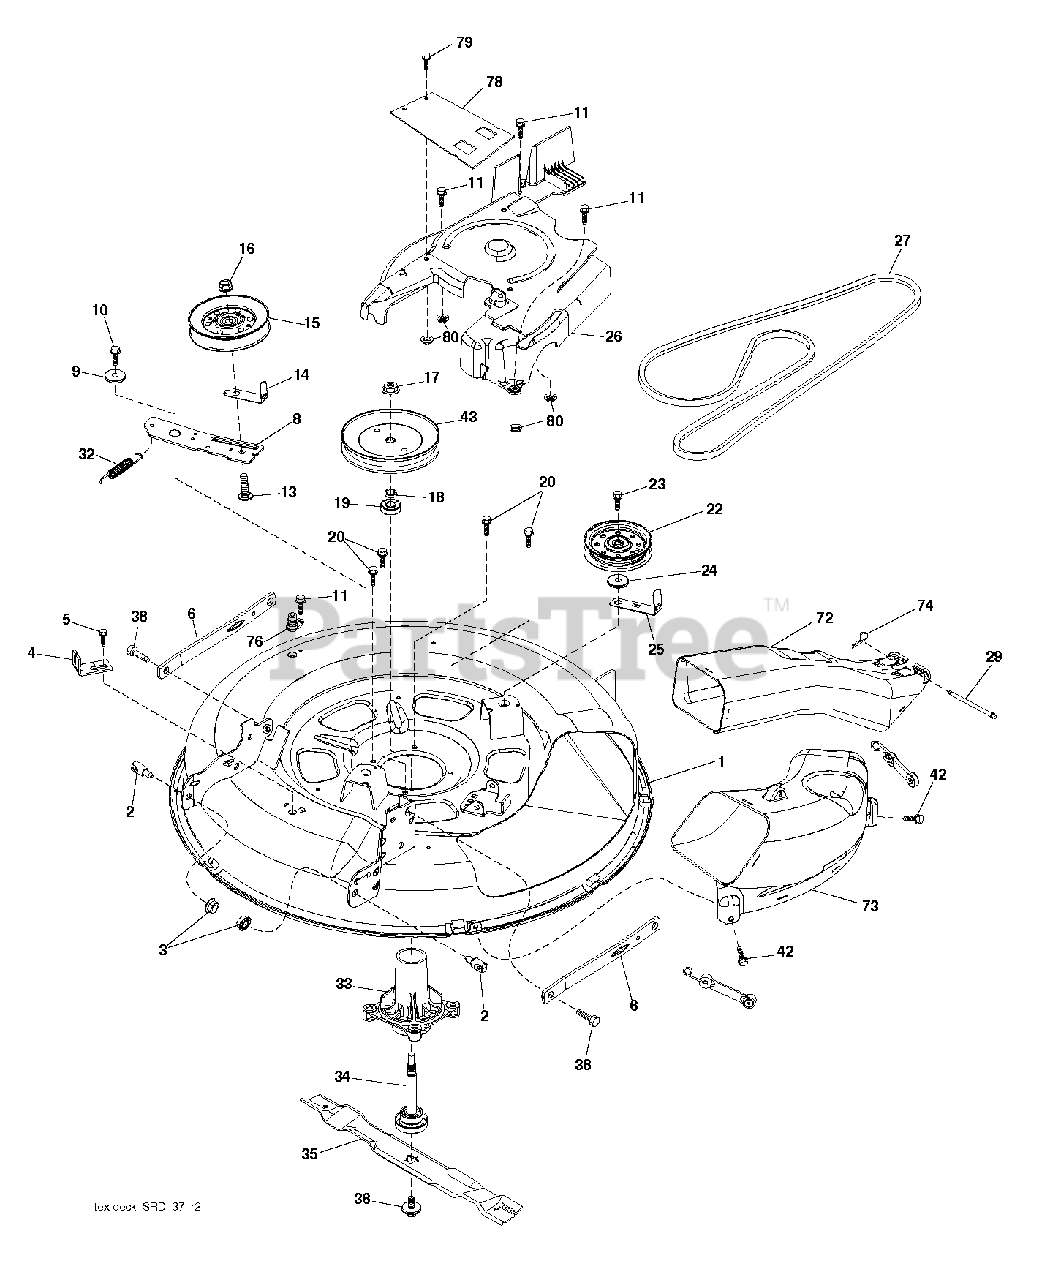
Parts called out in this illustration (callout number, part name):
2	STUD.FASTNER.W/ANTI-ROTATE
3	NUT LOCK HEX FLANGE 5/16-18
5	BOLT.5/16HEX.WHS.HD
6	ARMS.SUSP.MOWER.REAR.SRD
9	SPACER.RETAINER
10	SCREW 3/8-16X1
11	SCREW.1/4-20X5/8
13	BOLT.3/8-16X1.50
14	KEEPER, BELT IDLER
15	PULLEY.IDLER.4.25
16	NUT LOCK FLG 3/8-16 UNC
17	NUT.FLANGE.LOCK.TOP
18	WASHER.SPACER.MANDREL
20	SCREW, WASHER HEAD
22	PULLEY.IDLER.FLAT.46.PR.DR.
23	SCREW LT
27	V-BELT.DRIVE.MOWER.30"
32	SPRING.MOWER.DRIVE.ELECTRIC
33	HOUSING MANDREL
34	SHAFT.ASM.MDRL.N/GREASE.38
35	BLADE.MOWER.BAGGING.30"
36	BOLT.WASHER.ASM.7/16-2
38	BOLT.SHOULDER
42	SCREW, 3/8-16X3/4
43	PULLEY, MANDREL 6.5 PD
74	RETAINER-SPRNG RB
76	PORT.WASHOUT
79	SCREW.HI-LO.CONSOLE
80	PALNUT 1/4
